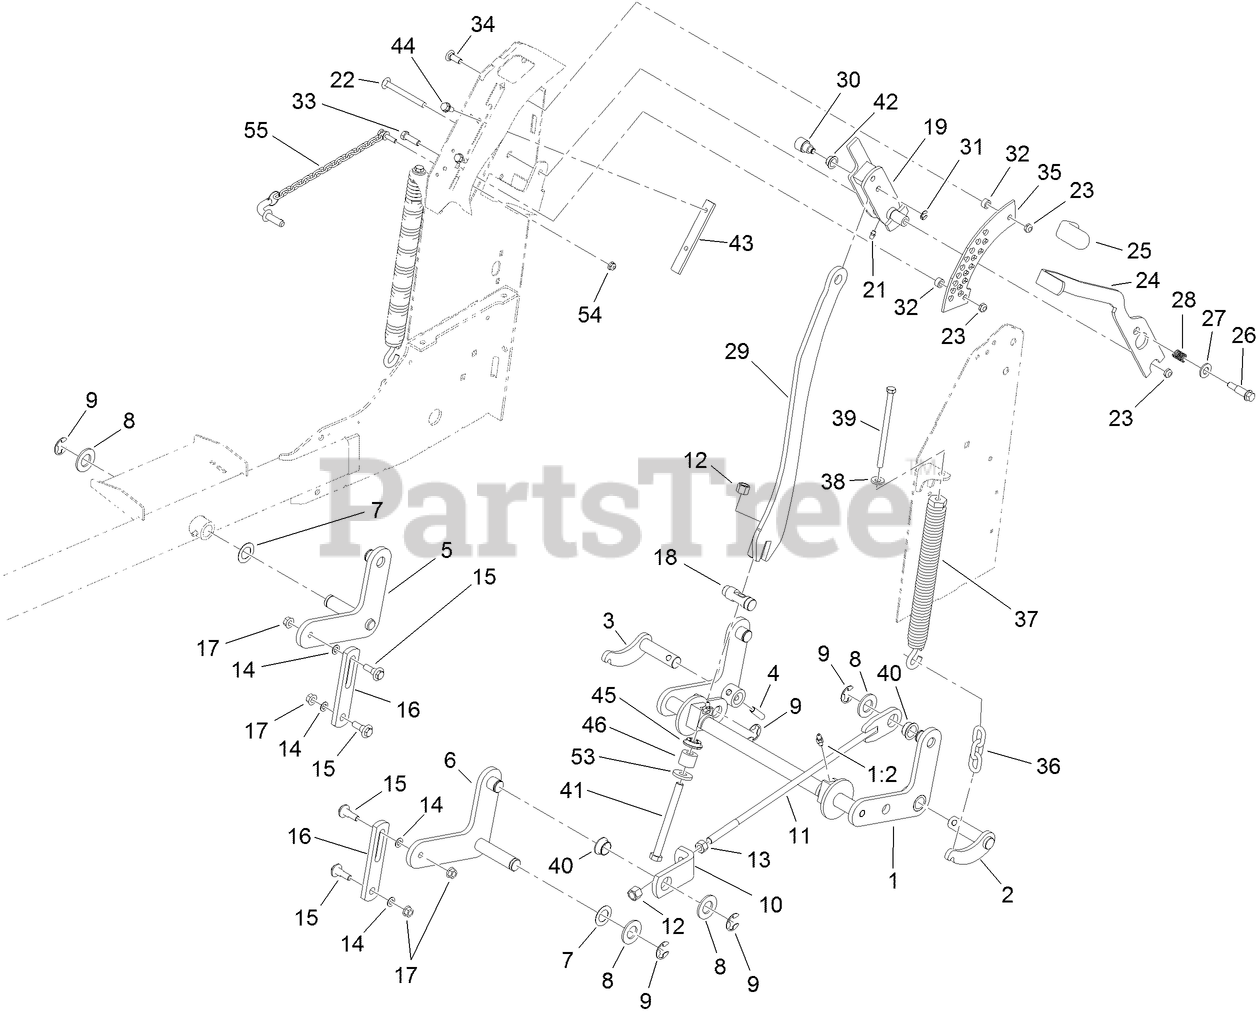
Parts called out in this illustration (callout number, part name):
1	REAR CROSSSHAFT ASM
1:2	FITTING-LUBE, 45 DEG
2	SHAFT-PIVOT, LH
3	SHAFT-PIVOT, RH
4	PIN-SPIRAL
5	ARM-LIFT, RH
6	ARM-LIFT, LH
7	WASHER-THRUST
8	WASHER-FLAT
9	RING-RETAINING, EXT
10	BRACKET-LIFT ROD
11	LIFT ROD ASM
12	NUT-LOCK, NI
13	NUT-HH
14	WASHER
15	SCREW-SHOULDER, HHF
16	LINK-LIFT
17	NUT-HF
18	PIN-HOC
19	HOC HANDLE ASM
21	FITTING-GREASE
22	SCREW-CARR
23	NUT-LOCK, NI
24	LEVER-HOC
25	GRIP-LEVER
26	SCREW-SHOULDER
27	WASHER-FLAT
28	SPRING
29	BAR-LIFT
30	HUB-PIVOT
31	RING-RETAINING
32	SPACER
33	SCREW-HH
34	SCREW-CARR
35	BRACKET-HOC
36	CHAIN-DECKLIFT
37	SPRING-EXTENSION
38	WASHER-BELLEVILLE
39	BOLT-TAP, HH
40	BEARING-FLANGE
41	SCREW-HH
42	BEARING-FLANGE
43	SKID-HANDLE, LIFT
44	SCREW-HWHTF
45	SEAT-SPRING
46	SPRING-URETHANE
53	WASHER
54	NUT-HF
55	HOC PIN ASM
